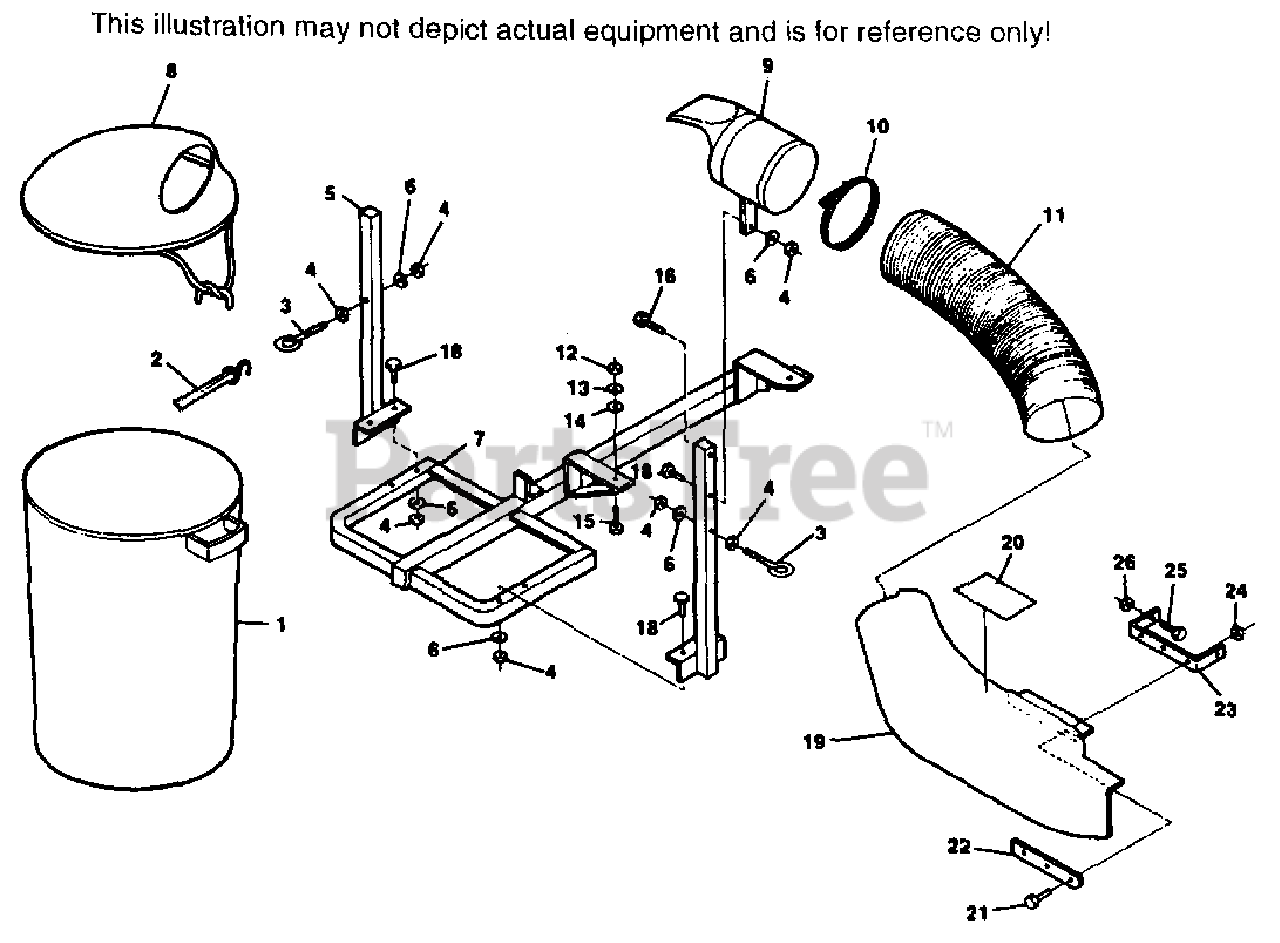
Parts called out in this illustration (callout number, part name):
1	BUCKET, GRASS CATCHER
2	RUBBER STRAP
3	EYEBOLT, 5/16-18 X 2-3/4
5	VERTICAL SPRT-REAR
7	FRAME WELDMENT
8	HOOD
9	DEFLECTOR WELDMENT
10	CLAMP-7"
11	TUBE-7"
14	WASHER, 25/64 X 15/16 X 12 GA.
19	BOOT ASSEMBLY(INC. 20)
20	DECAL-DANGER
22	REINFORCEMENT-BOOT MTNG.
23	BRACKET-BOOT MOUNTING
24	HEX NUT 1/4-20 ELSTC. STOP
26	HEX NUT, 5/16-18 ELSTC. STOP
